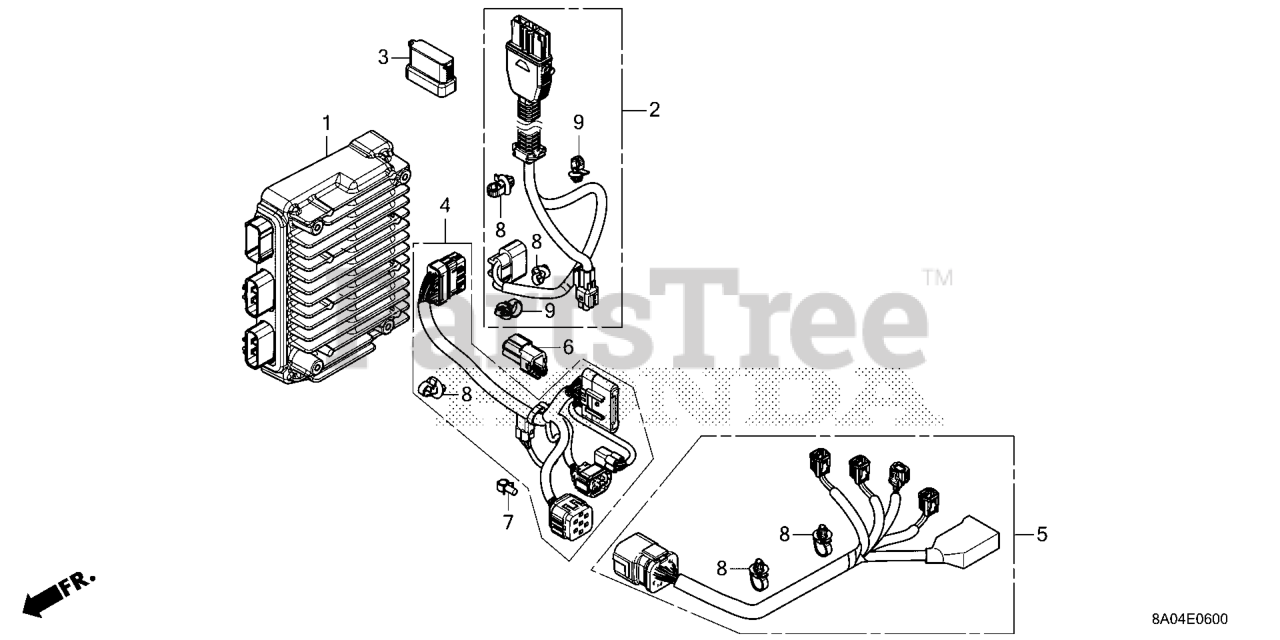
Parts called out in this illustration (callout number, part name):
2	CABLE ASSY., POWER
4	WIRE HARNESS, MAIN
6	CONNECTOR, DUMMY (4P)
7	CLIP, BRAKE PIPE (A) (FOR NEUTRAL SWITCH)
8	CLIP, HARNESS BAND (145MM) (BLACK)
9	CLIP, HARNESS BAND (164.5MM) (DARK BLUE)
